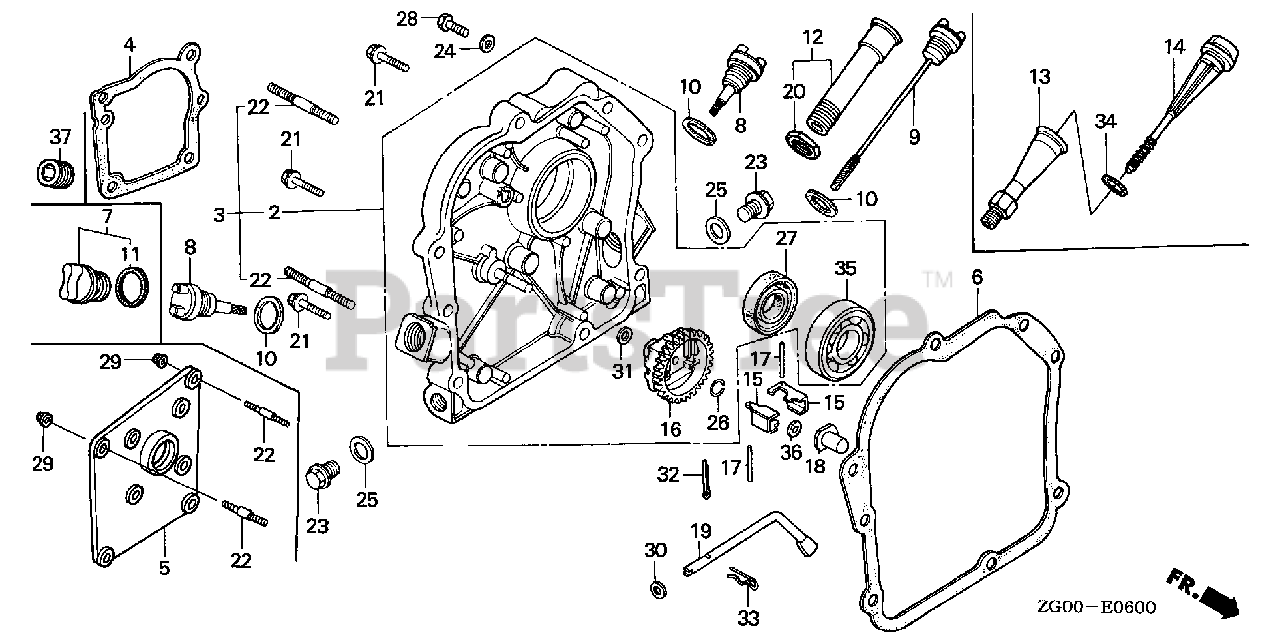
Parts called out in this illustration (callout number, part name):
2	COVER ASSY., CRANKCASE
6	GASKET, CASE COVER
7	CAP ASSY., OIL FILLER
8	CAP, OIL FILLER
10	GASKET, OIL FILLER CAP
11	GASKET, OIL FILLER CAP
15	WEIGHT, GOVERNOR
16	HOLDER, GOVERNOR WEIGHT
17	PIN, GOVERNOR WEIGHT
18	SLIDER, GOVERNOR
19	SHAFT, GOVERNOR ARM
21	BOLT, FLANGE (6X28)
23	BOLT, DRAIN PLUG
25	WASHER, DRAIN PLUG (10.2MM)
26	CLIP, GOVERNOR HOLDER
27	OIL SEAL (17X30X6) (NOK)
30	WASHER, PLAIN (5MM)
31	WASHER, PLAIN (6MM)
33	PIN, LOCK (8MM)
35	BEARING, RADIAL BALL (6203)
